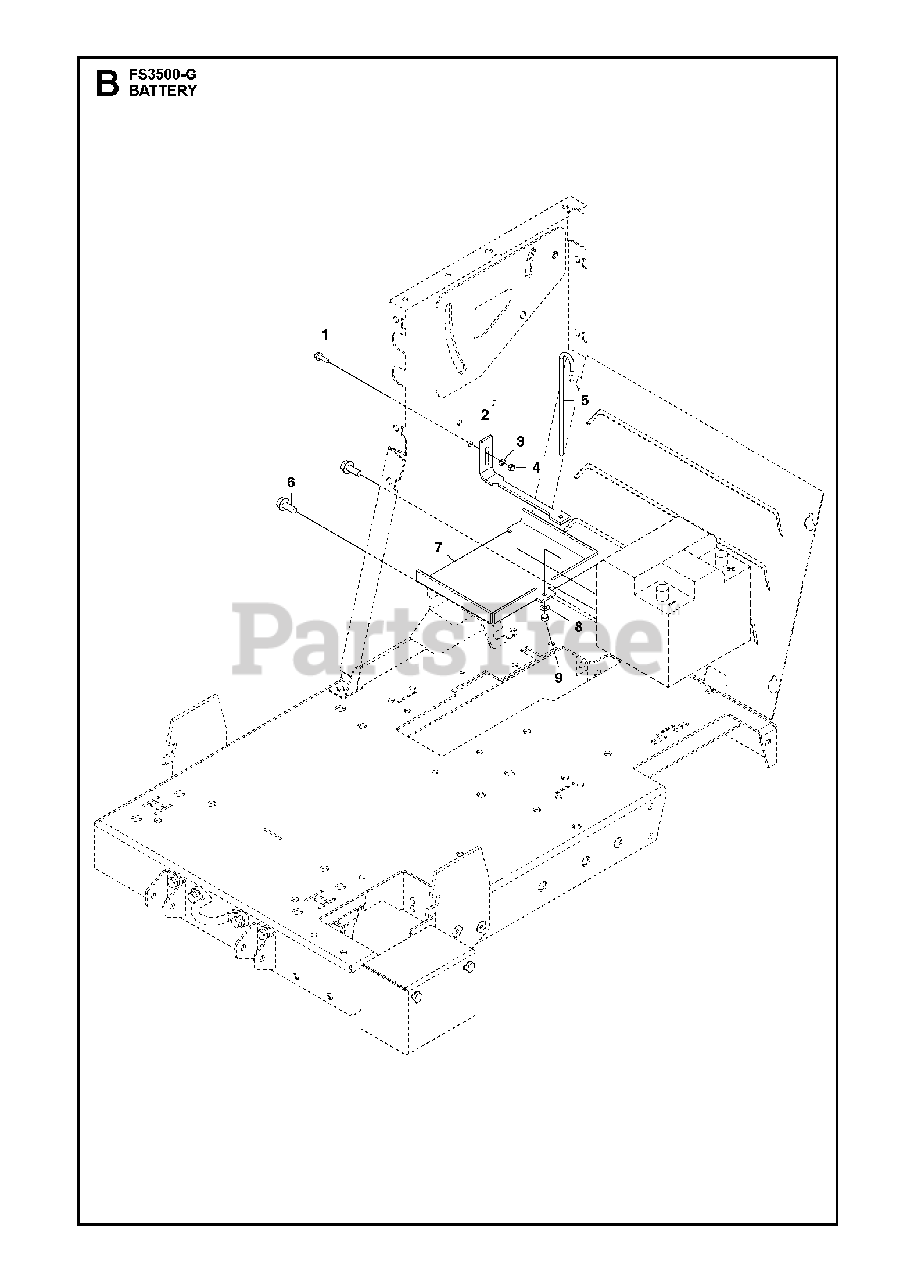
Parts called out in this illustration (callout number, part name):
4	HEXAGON LOCKING NUT
8	WASHER 1/4 SAE
9	NUT
